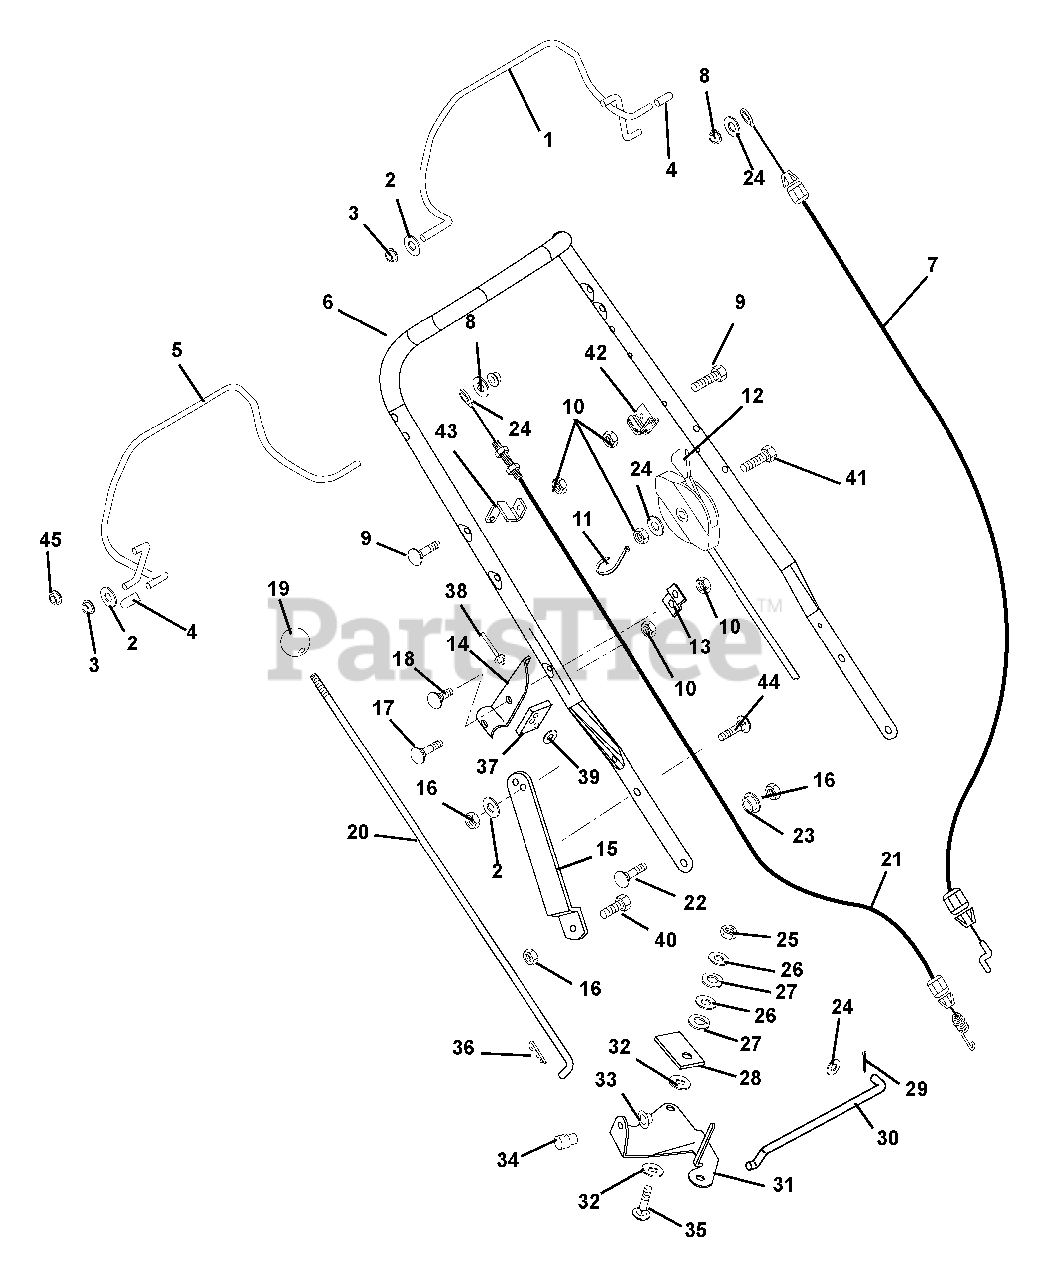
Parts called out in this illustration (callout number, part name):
1	Engine Bail Weldment
2	Washer, Flat Steel .32 x .44 x .44 x .56
3	Bushing, Flange .325 x .688 x .56
4	Cap, Vinyl .25 I.D.
5	Traction Bail Weldment
6	Handlebar
7	Cable, Engine
8	Ring, Retaining External .25 x .01
9	Bolt, Round Head Square Neck .25-20 x 1.25
10	Nut, Locking Center .25-20
11	Cable Tie
12	Control, Throttle - Honda
13	Brace, Speed Control
14	Bracket, Speed Control
15	Handlebar Bracket
16	Nut, Locking Center .31-18
17	Bolt, Round Head Square Neck .25-20 x 1.38
18	Bolt, Round Head Square Neck .25-20 x .50 Grade 5
20	Rod, Speed Control
21	Traction Cable
22	Bolt, Round Head Square Neck .31-18 x 1.00 Grade 5
23	Shoulder Spacer
24	Washer, Flat Steel .281 x .62 x .065
25	Nut, Locking Center .38-16
26	Washer, Flat Steel .406 x .812 x .065
27	Washer, Lock .375 x .115 Heavy
28	Pressure Flange
29	Pin, Cotter .06 x .50
30	Shift Link
31	Bell Crank, Speed Control
32	Friction Washer
33	Cap, Rod .375
35	Bolt, Round Head Square Neck .38-16 x 1.25
36	Pin, Hair Internal .08 x .18 x 1.18
37	Support Pad
38	Rivet .187 x .575
39	Washer, Flat Steel .219 x .50 x .049
40	Bolt, Hex .31-18 x .75 Grade 5
41	Bolt-Hex .25-20 x 2.50 Grade 5
42	Anchor, WBLM Engine Cable
43	Anchor Cable
44	Bolt, Round Head Square Neck .31-18 x .75 Grade 5
45	Push Nut .312
